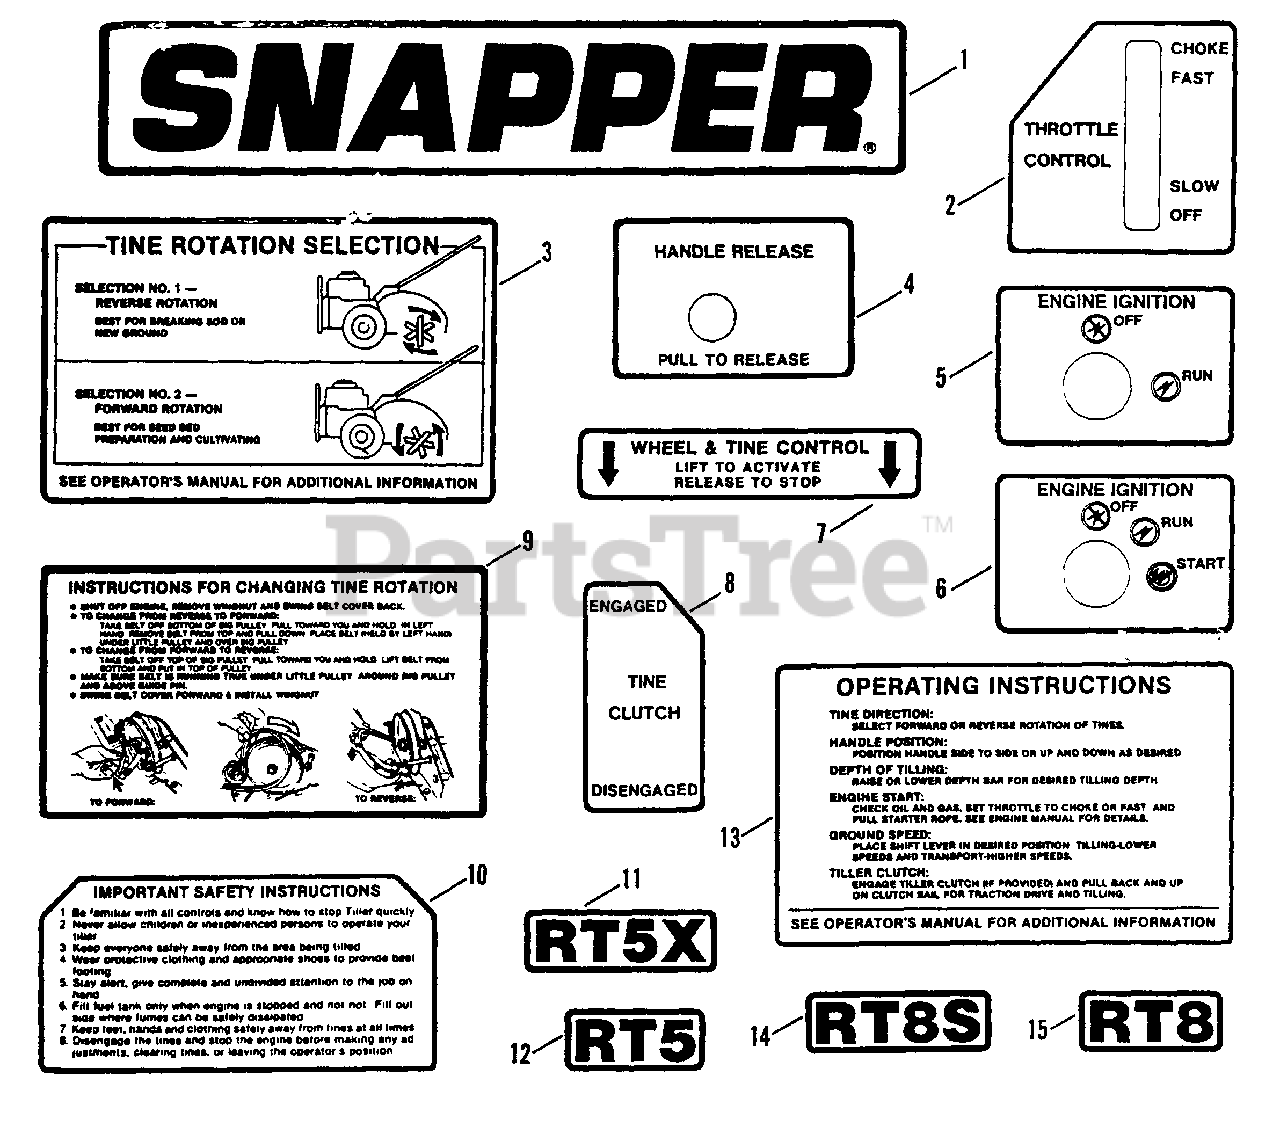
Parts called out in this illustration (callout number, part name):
1	DECAL, SNAPPER (14.56 x 2.75")
1	DECAL, SNAPPER (11.5 x 2.25")
2	DECAL, Throttle Control
3	DECAL, Tine Rotation Selection
4	DECAL, Handle Release
5	(NLA) DECAL, Engine Ignition (Manual Start)
6	DECAL, Engine Ignition (Elec. Start)
7	DECAL, Wheel & Tine Control
8	DECAL, Tine Clutch
9	DECAL, Belt Rotation Instruction
10	DECAL, Safety instructions
11	(NLA) DECAL, Model RT5X
12	DECAL, Model RT5
13	DECAL, Operating Instructions
14	DECAL, Model RT8S
15	(NLA) DECAL, Model RT8
